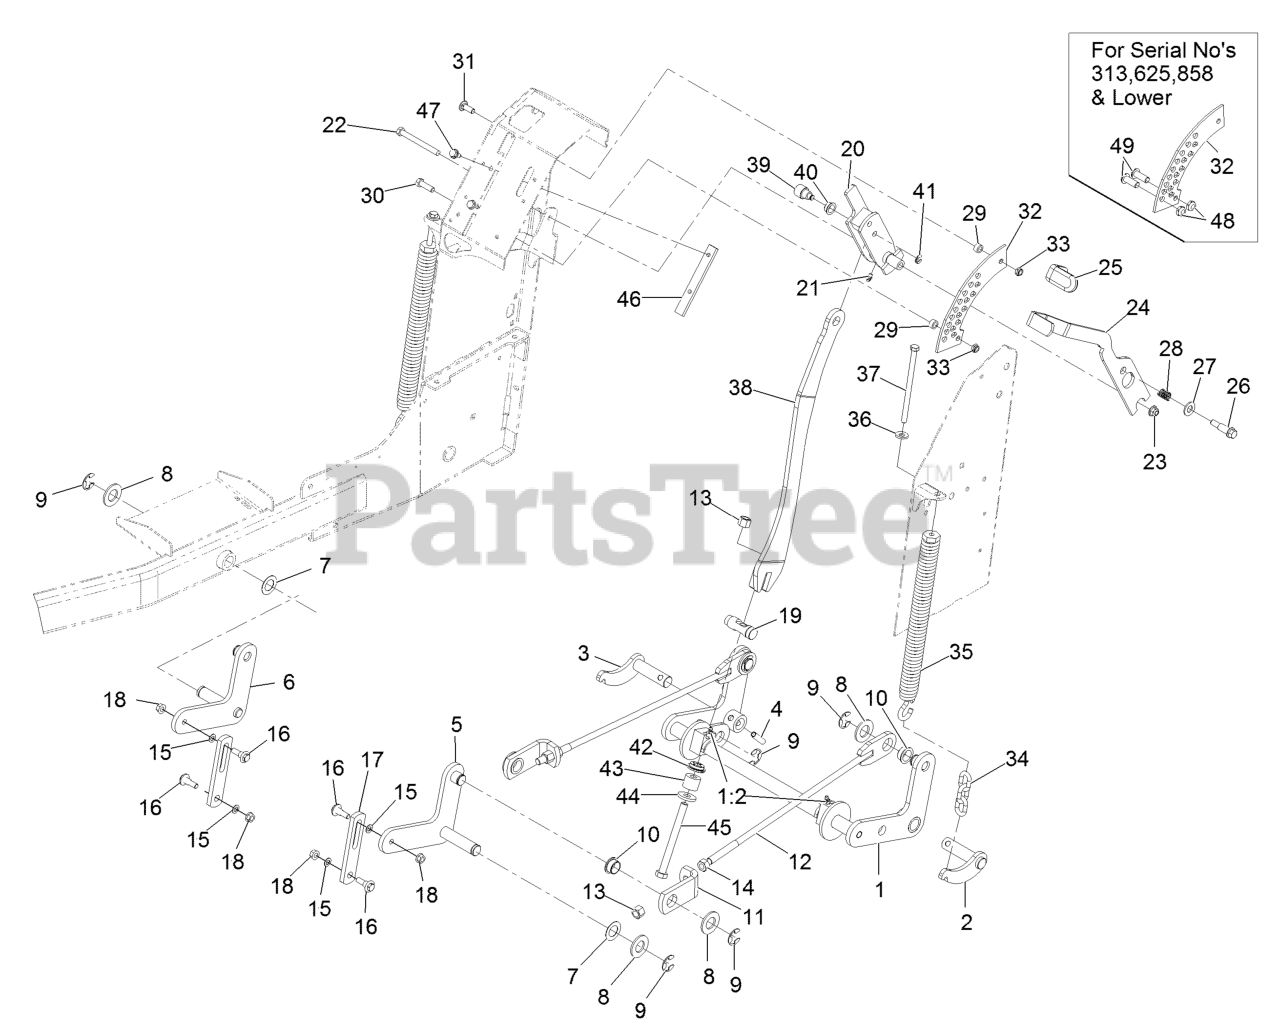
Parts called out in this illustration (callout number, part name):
1	REAR CROSSSHAFT ASM
1:2	FITTING-LUBE, 45 DEG
2	SHAFT-PIVOT, LH
3	SHAFT-PIVOT, RH
4	PIN-SPIRAL
5	ARM-LIFT, LH
6	ARM-LIFT, RH
7	WASHER-THRUST
8	WASHER-FLAT
9	RING-RETAINING, EXT
10	BEARING-FLANGE
11	BRACKET-LIFT ROD
12	LIFT ROD ASM
13	NUT-LOCK, NI
14	NUT-HH
16	SCREW-SHOULDER, HHF
17	LINK-LIFT
19	PIN-HOC
20	HOC HANDLE ASM
21	FITTING-GREASE
22	SCREW-HH
23	NUT-HF, NI
24	LEVER-HOC
25	GRIP-LEVER
26	SCREW-SHOULDER
27	WASHER-FLAT
29	SPACER
30	SCREW-HH
31	SCREW-CARR
32	BRACKET-HOC
34	CHAIN-DECKLIFT
35	SPRING-EXTENSION
36	WASHER-BELLEVILLE
37	BOLT-TAP, HH
38	BAR-LIFT
39	HUB-PIVOT
40	BEARING-FLANGE
41	RING-RETAINING
42	SEAT-SPRING
43	SPRING-URETHANE
45	SCREW-HH
46	SKID-HANDLE, LIFT
47	Screw-HWH 5/16-18 X 3/4 Tf
49	SCREW-HSBH
